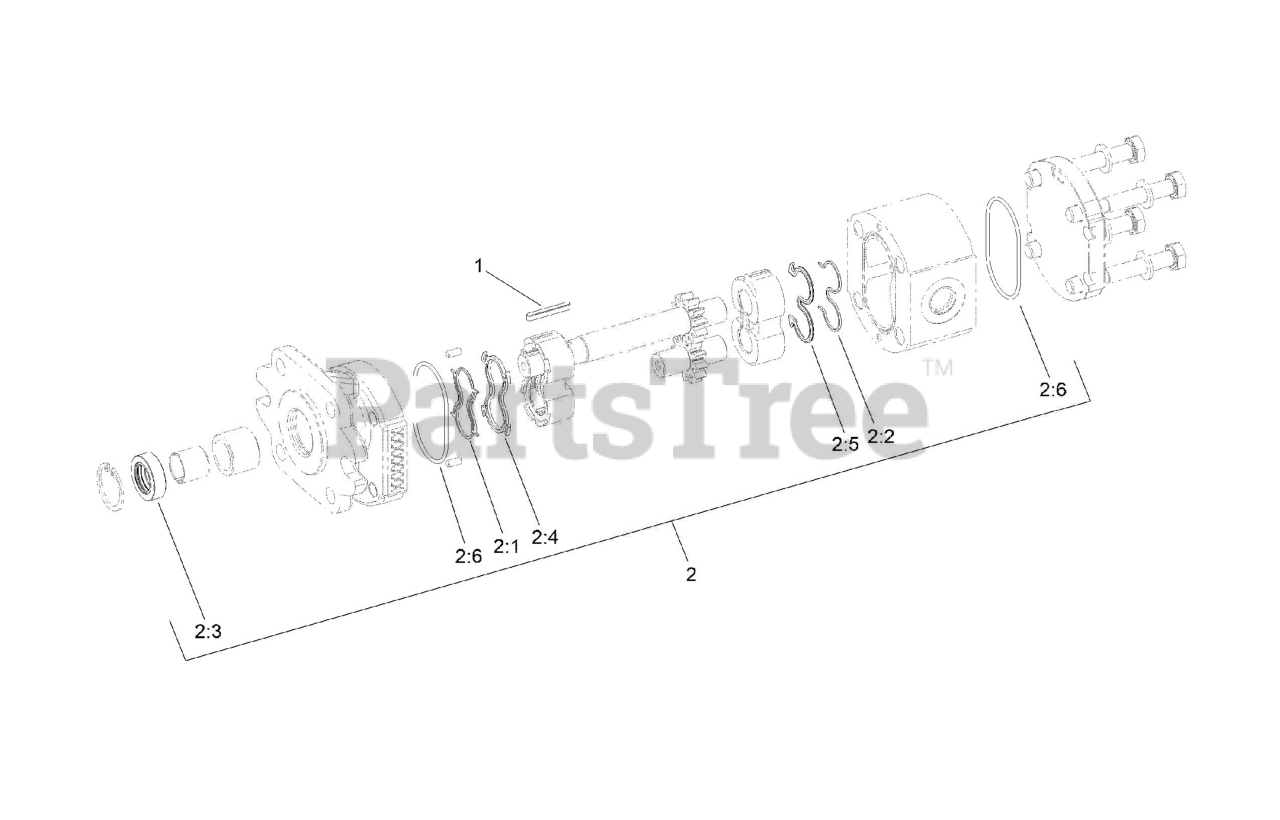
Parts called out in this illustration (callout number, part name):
1	KEY-SQUARE
2	SEAL KIT
2:1	Seal-Anti Extrusion
2:2	Seal-Anti Extrusion
2:3	Seal-Shaft
2:4	Seal-Upper
2:5	Seal
2:6	O-Ring
